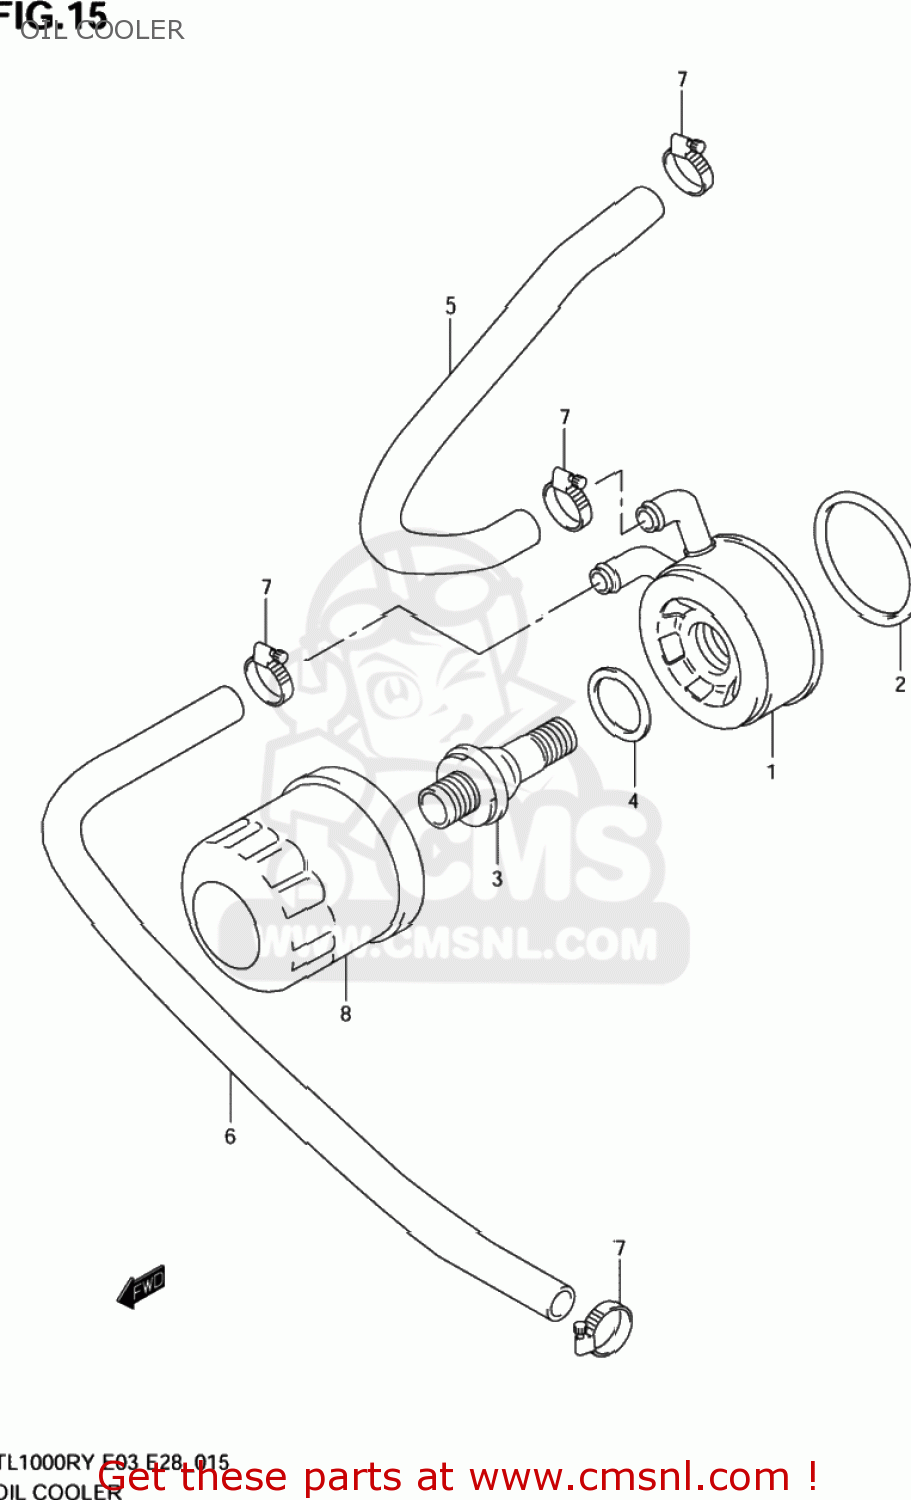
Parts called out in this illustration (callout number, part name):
1	COOLER ASSY,OIL
2	O RING(D:3.1,ID:63.9)
3	BOLT,OIL COOLER UNION
4	SHIM(25X34X0.7)
5	HOSE,OIL COOLER INLET
6	HOSE,OIL COOLER OUTLET
7	CLAMP
8	FILTER ASSEMBLY,ENGINE OIL
